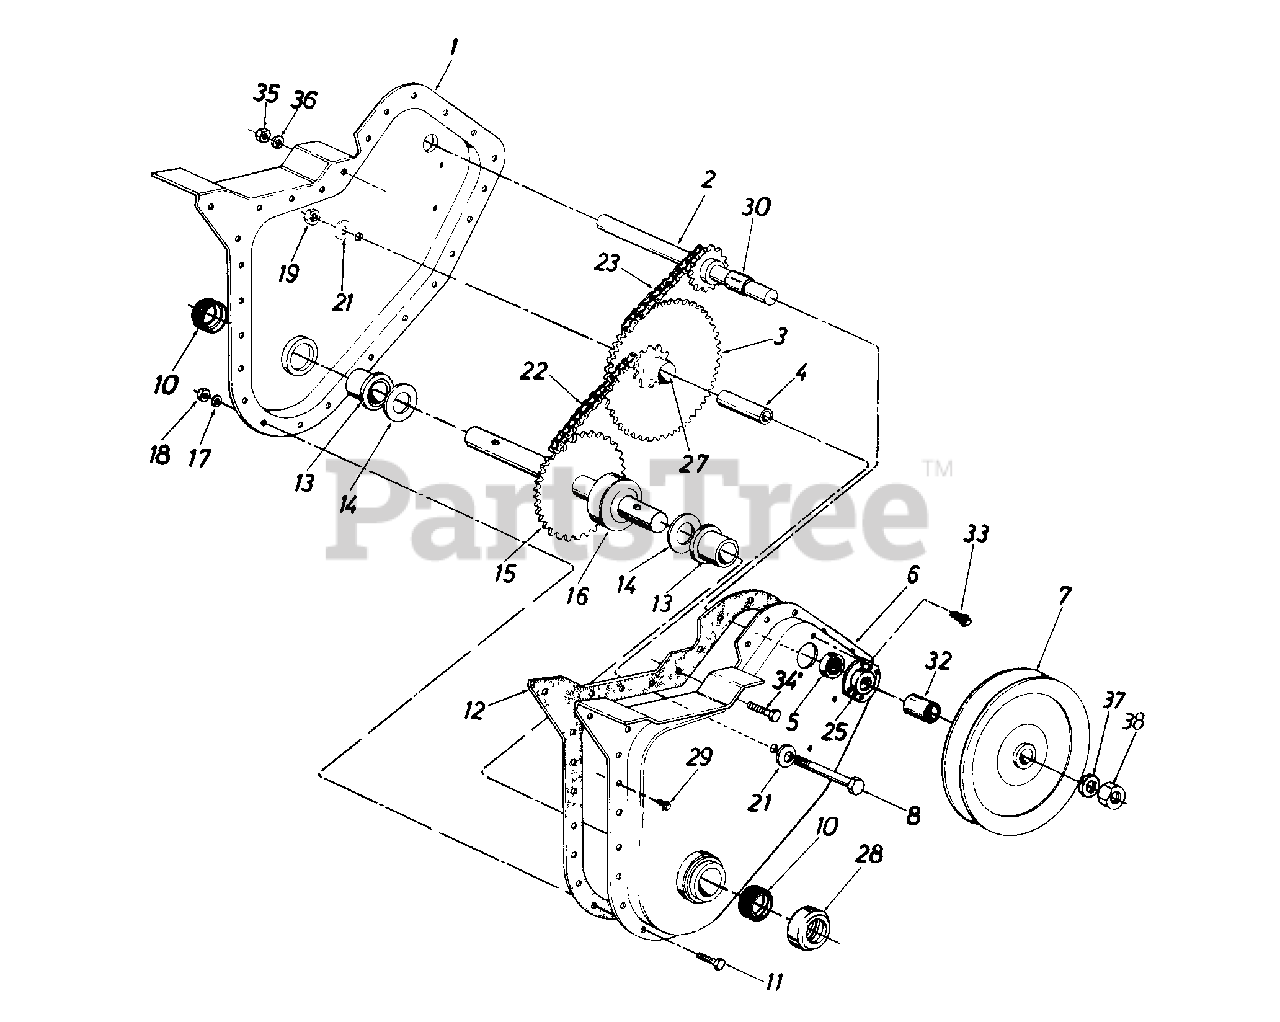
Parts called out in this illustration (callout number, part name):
3	Hub and Sprocket Ass'y.
4	Bearing Inner Race
5	Ball Bearing
6	Chain Case Ass'y.- L.H.
7	Pulley - Chain Case
8	Hex Bolt 3/8-24 x 2.5"
10	Seals
11	Hex Bolt 1/4-28 x .625"
12	Gasket
13	Flange Brg..879" I.D.
14	FI-Wash..88" I.D. x 1.5"
15	Tine Shaft Ass'y.
16	Spacer 7/8" I.D.
17	L-Wash. 1/4" I.D.
18	Hex Nut 1/4-28 Thd.
19	Hex Ins. L-Nut 3/8-24 Thd.
21	Bell-Wash..406" I.D.
22	Chain #420 1/2" Pitch 38 Links
23	Chain #35 .375" Pitch 50 Links
25	Bearing Housing
28	Dust Cap
29	Hex Wash. Hd. Self-Tap Scr. 1/4-20 x .50" Lg.
30	Spacer.63" I.D.x.77" O.D. x .38" Lg.
32	Spacer .647 x .77"
33	Hex Wash. Hd. Self-Tap Scr. 1/4-20 x .38" Lg.
34	Hex Bolt 5/16-18 x .75" Lg.
35	Hex Nut 5/16-18 Thd.
36	L-Wash. 5/16" I.D.
37	Bell-Wash..38" I D. x.88" O.D.
38	Hex Flange L-Nut 3/8-24 Thd.
